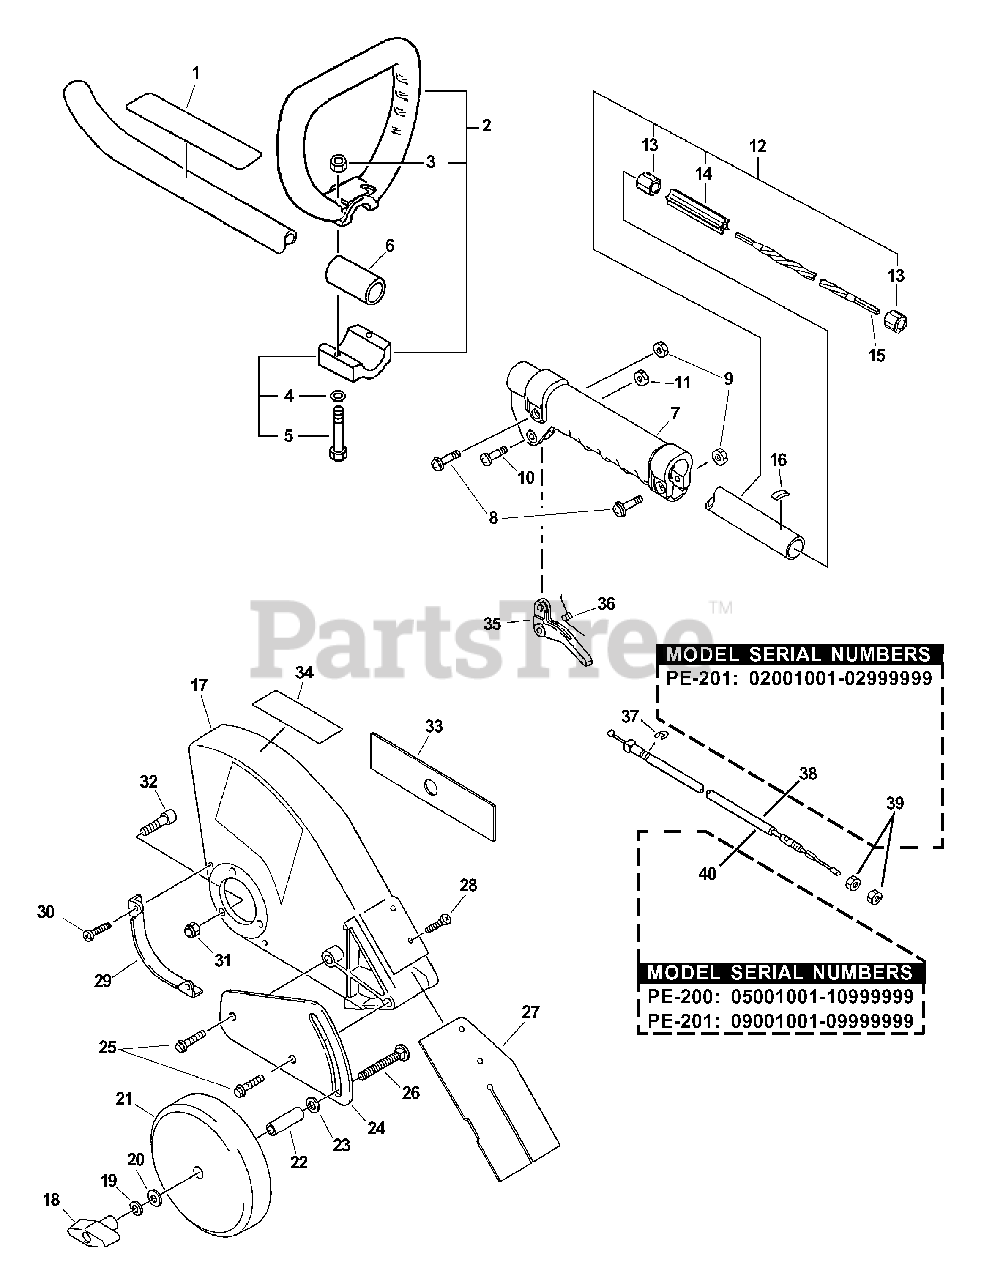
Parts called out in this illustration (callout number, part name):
1	LABEL, CAUTION
2	LOOP HANDLE ASSY
3	NUT M5
4	WASHER, FLAT 5.5×10×0.8
5	SCREW 5×40
8	SCREW - 5×25
9	NUT M5
11	NUT, LOCK M5
12	MAIN PIPE ASSY
14	LINER - FLEXIBLE
15	DRIVESHAFT - FLEXIBLE L= 1522
16	LABEL - ALIGNMENT
17	SHIELD, DEBRIS
18	KNOB, FASTENER
19	WASHER, SPRING 8
21	WHEEL
22	COLLAR 12
23	WASHER, SPRING 10
24	BRACKET, WHEEL
26	BOLT 5/16"-18×2-1/2"
27	FLAP, DEBRIS
29	GUARD, SHIELD
31	NUT, LOCK M5
32	BOLT 5×22
33	BLADE - 2 PK
34	LABEL, CAUTION
35	TRIGGER, THROTTLE
36	SPRING, THROTTLE
37	RING, RETAINING - 5
38	CABLE, THROTTLE
39	NUT M6
40	CABLE, THROTTLE
